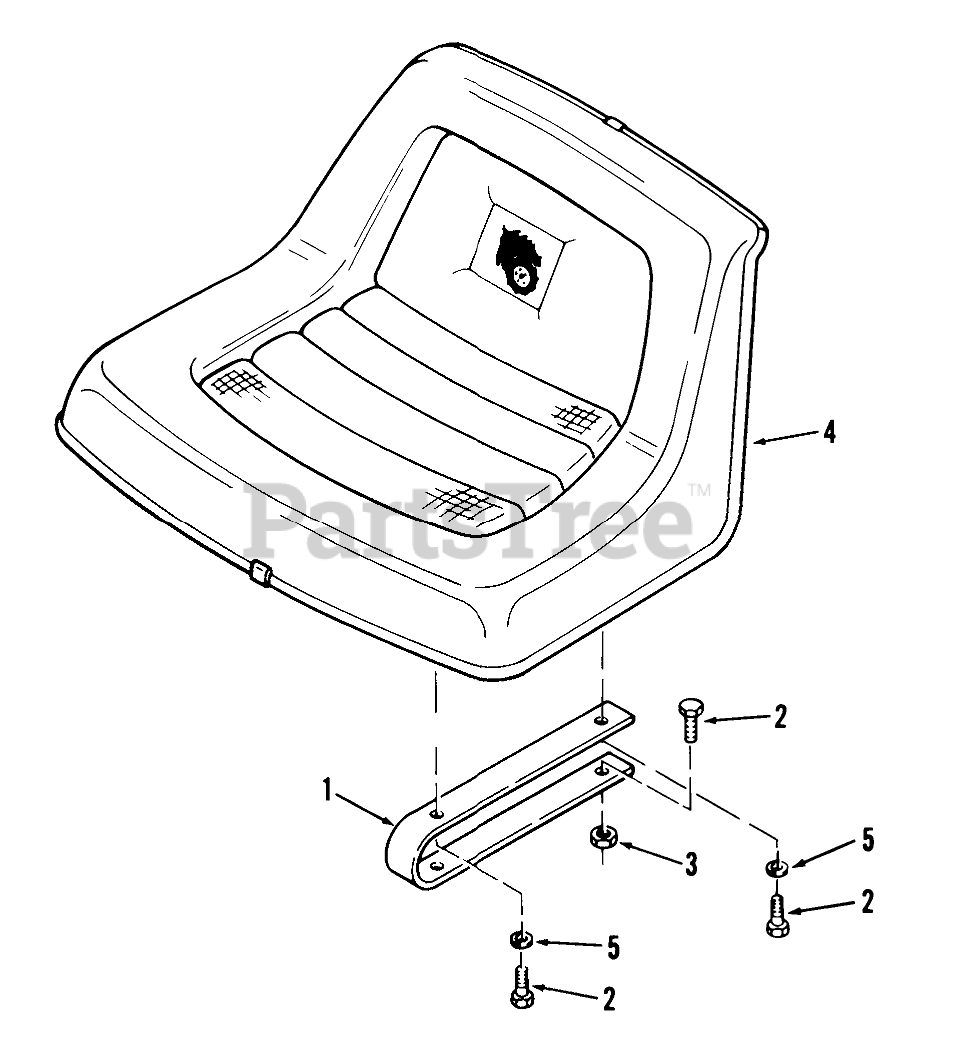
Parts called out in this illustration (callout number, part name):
1	Spring
2	Bolt
3	Nut
4	Seat
5	Lockwasher
